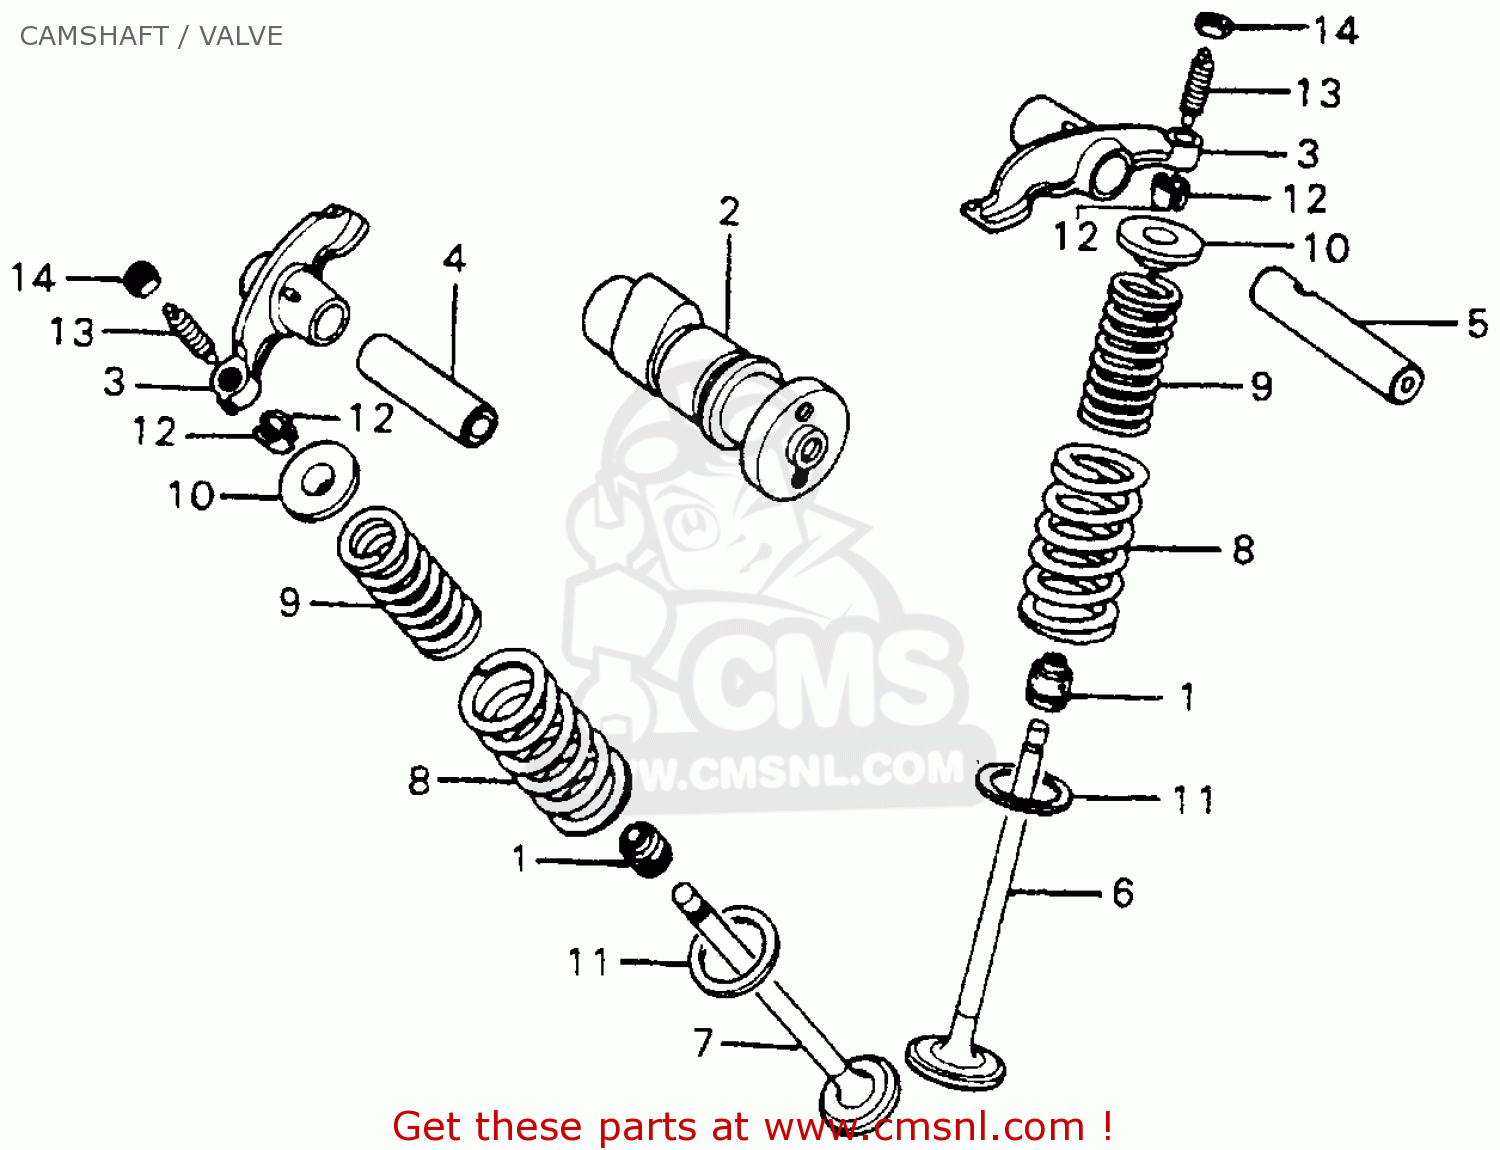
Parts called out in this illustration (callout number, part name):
1	SEAL,VALVE STEM
2	CAMSHAFT
3	ARM,VALVE ROCKER
4	SHAFT, ROCKER ARM
5	SHAFT,ROCKER ARM
6	VALVE, INLET
7	VALVE,EX.
8	SPG.,VALVE OUTER
9	SPRING,VALVE
10	RETAINER
11	SEAT,OUTER
12	COTTER,VALVE
13	SCREW,TAPPET ADJ.
14	NUT, TAPPET.
